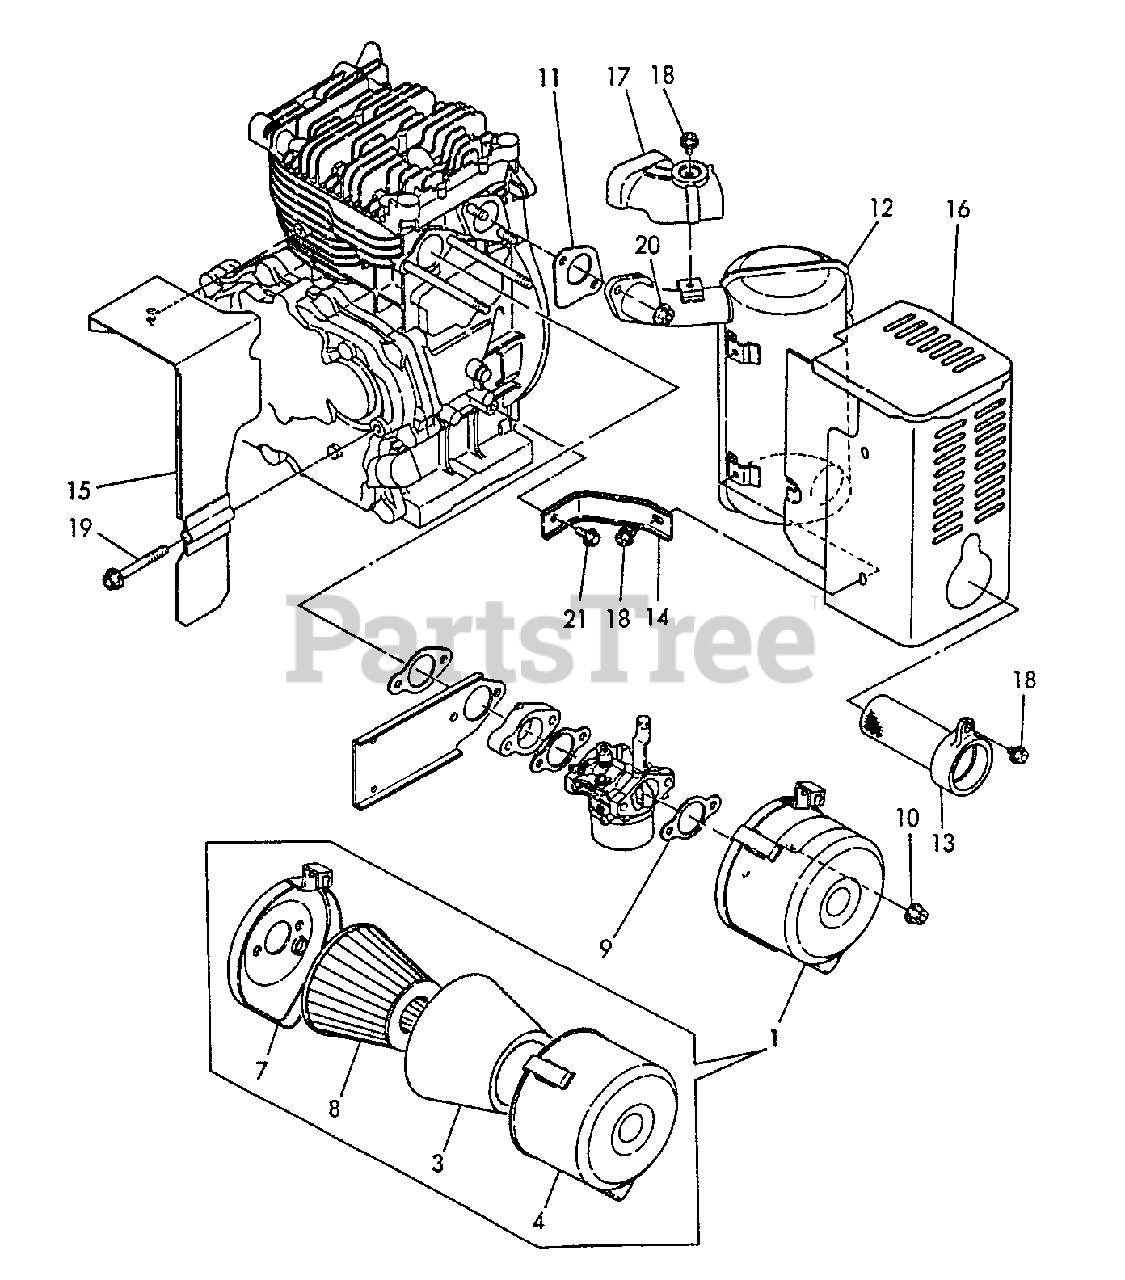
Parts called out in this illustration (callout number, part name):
1	CLEANER ASSY, AIR
3	FILTER, AIR
4	BODY ASSY
7	PLATE
8	ELEMENT
9	GASKET, INTAKE
10	U-NUT M8
11	GASKET, EXHAUST
12	MUFFLER
13	SCREEN, SPARK ARRESTER
14	STAY, MUFFLER
15	PLATE, GUIDE
16	COVER, MUFFLER
17	COVER-C, MUFFLER
18	BOLT - 6×8 -- PLATED
19	BOLT - 8×60 -- PLATED
20	U-NUT M8
21	BOLT - 6×8 -- PLATED
